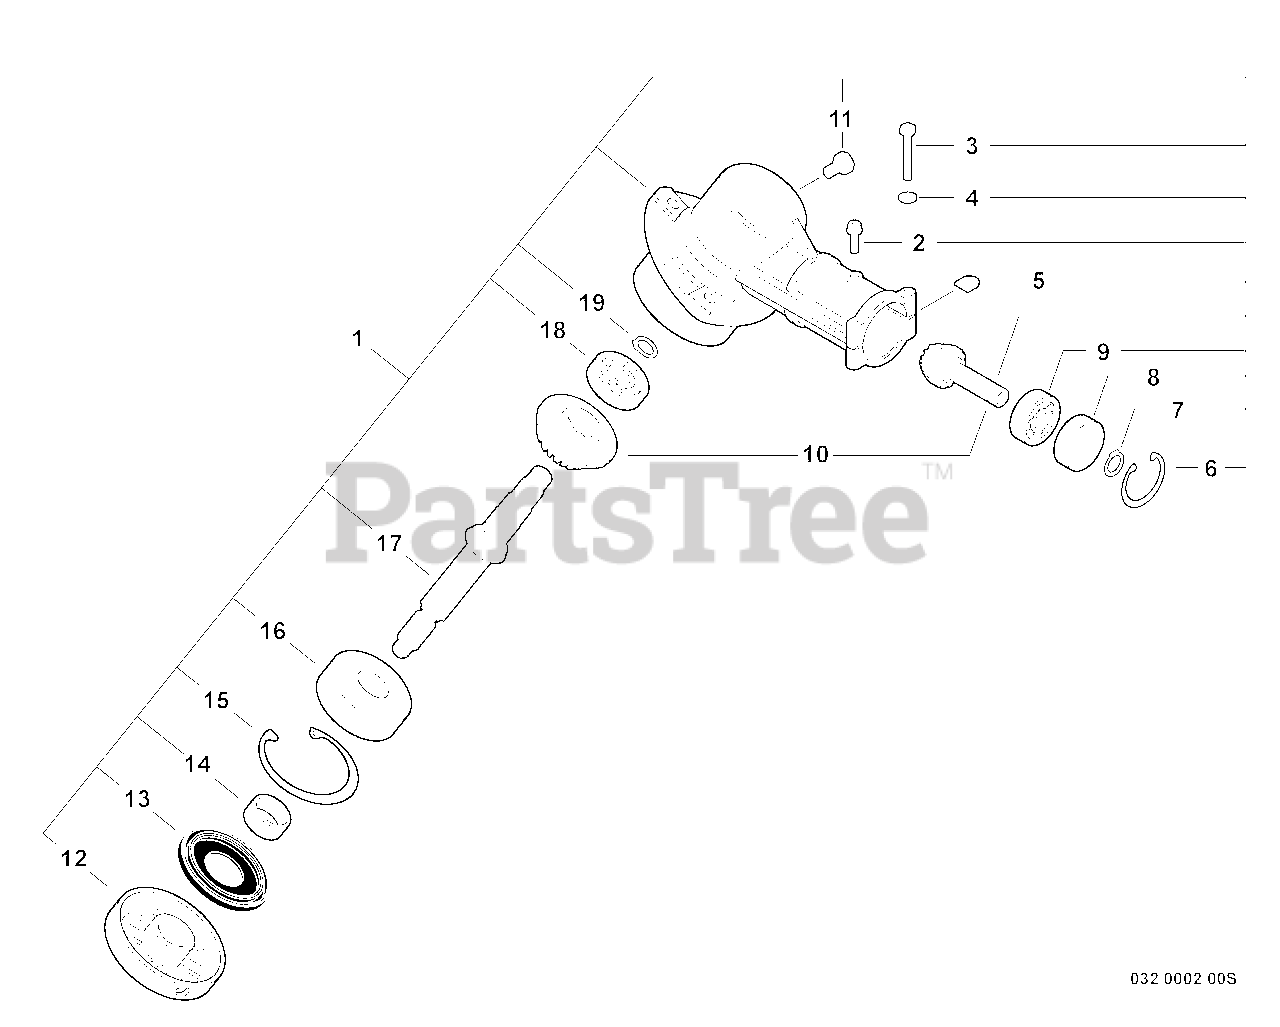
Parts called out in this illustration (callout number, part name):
1	GEAR CASE ASSY
2	SCREW - 5X10
3	BOLT - 5X35
4	WASHER - 5
6	RING, RETAINING - 22
7	RING, RETAINING - 10
8	BEARING, BALL - 6900Z
9	BEARING, BALL - 6900
10	GEAR SET - BEVEL
11	BOLT - 8X8
12	ADAPTOR, BLADE - UPPER
13	SEAL, OIL
15	RING, RETAINING - 32
16	BEARING, BALL - 6201
17	GEAR - SHAFT
18	BEARING, BALL - 609
19	RING, RETAINING - 12
